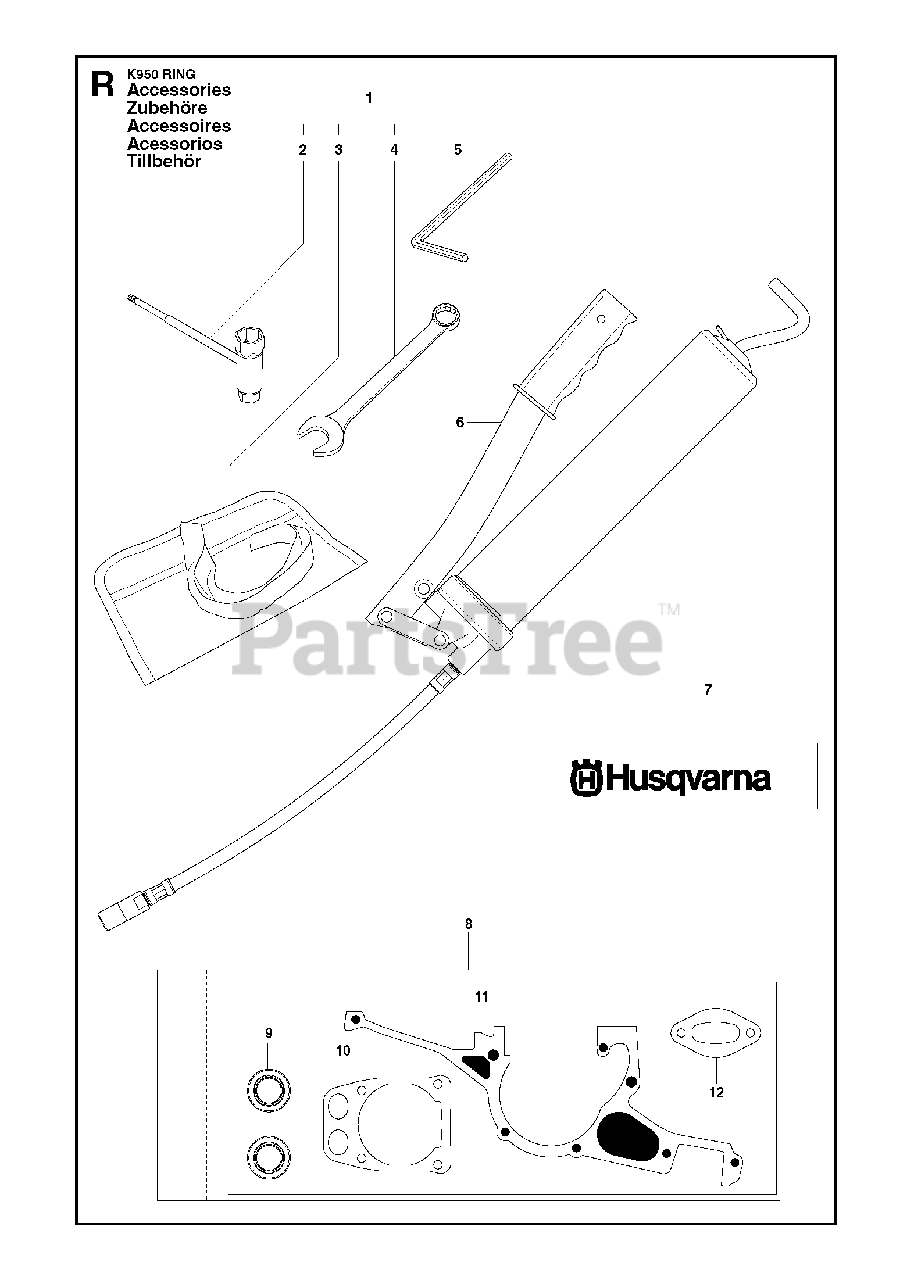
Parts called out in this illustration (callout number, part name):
7	GREASE
8	GASKET KITIncl. 9 - 12
9	SEALING RING
10	GASKET
11	GASKET
12	GASKET
